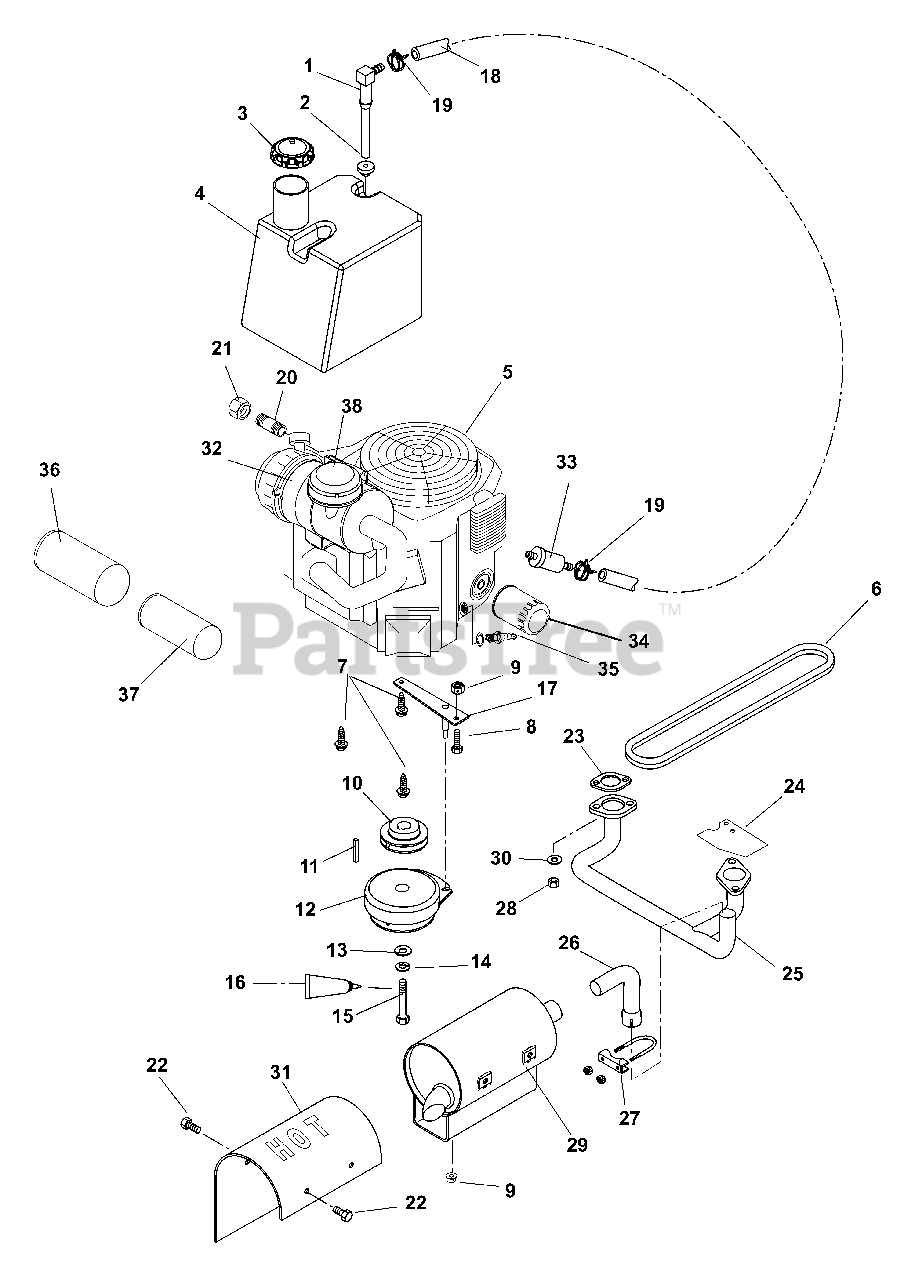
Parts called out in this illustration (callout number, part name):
1	Fitting, Tank
2	Bushing
3	Cap, Gas
4	Tank, Fuel
5	Engine, 27HP Kohler 6-Pin (021)
5	Engine, 25HP Kawasaki (022)
6	Hydraulic System V-Belt A-Section 24.90 x .500 /.031
7	Screw-Tapping Hex-Washer-Head .38-16 x 1.00
8	Bolt-Hex .31-18 x 1.75 Grade 5
9	Nut-Locking-Top-Flange .31-18
10	Pulley-4.46 Dia. x 1.12 Bore
11	Key-Square .25 x 1.00 x .25
12	Electric Clutch
13	Washer-Flat-Steel .515 x 1.625 x .250
14	Washer-Locking .44 x .109
15	Bolt-Hex .44-20 x 3.00 Grade 5
16	Loc-Tite™ 271 (Red)
17	Anchor-Clutch
18	Gas Line-Bulk 1/4" ID (021)
18	Gas Line-Bulk 1/4" ID (022)
19	Hose-Clamp
20	Nipple, Pipe .38 x 6.00 Unfinished Steel
21	Pipe Cap
22	Bolt, Hex M5 - .8 x 8 mm
23	Gasket-Exhaust
24	Heat Deflector (021)
25	Manifold-Kohler CV18-27 (021)
25	Manifold-Kawasaki, PM310 (022)
26	Tube, Manifold
27	U-Bolt, 1/4-20 x 1.50
28	Nut-Hex M8-1.25
29	Muffler (Includes 09066300 Heat Shield)
30	Washer-Locking .31 x .078
31	Heat Shield (Included with 09065600 Muffler)
32	Air Cleaner Assembly
33	Fuel Filter (022)
33	Fuel Filter (021)
34	Filter, Oil- Kohler CV20 (021)
34	Filter, Oil- Kawasaki (022)
35	Spark Plug (021)
35	Spark Plug (022)
36	Element, Outer Primary
37	Element, Inner Safety
38	Cap, Air Cleaner Intake
39	Cap, 2.5" Air Cleaner Intake
